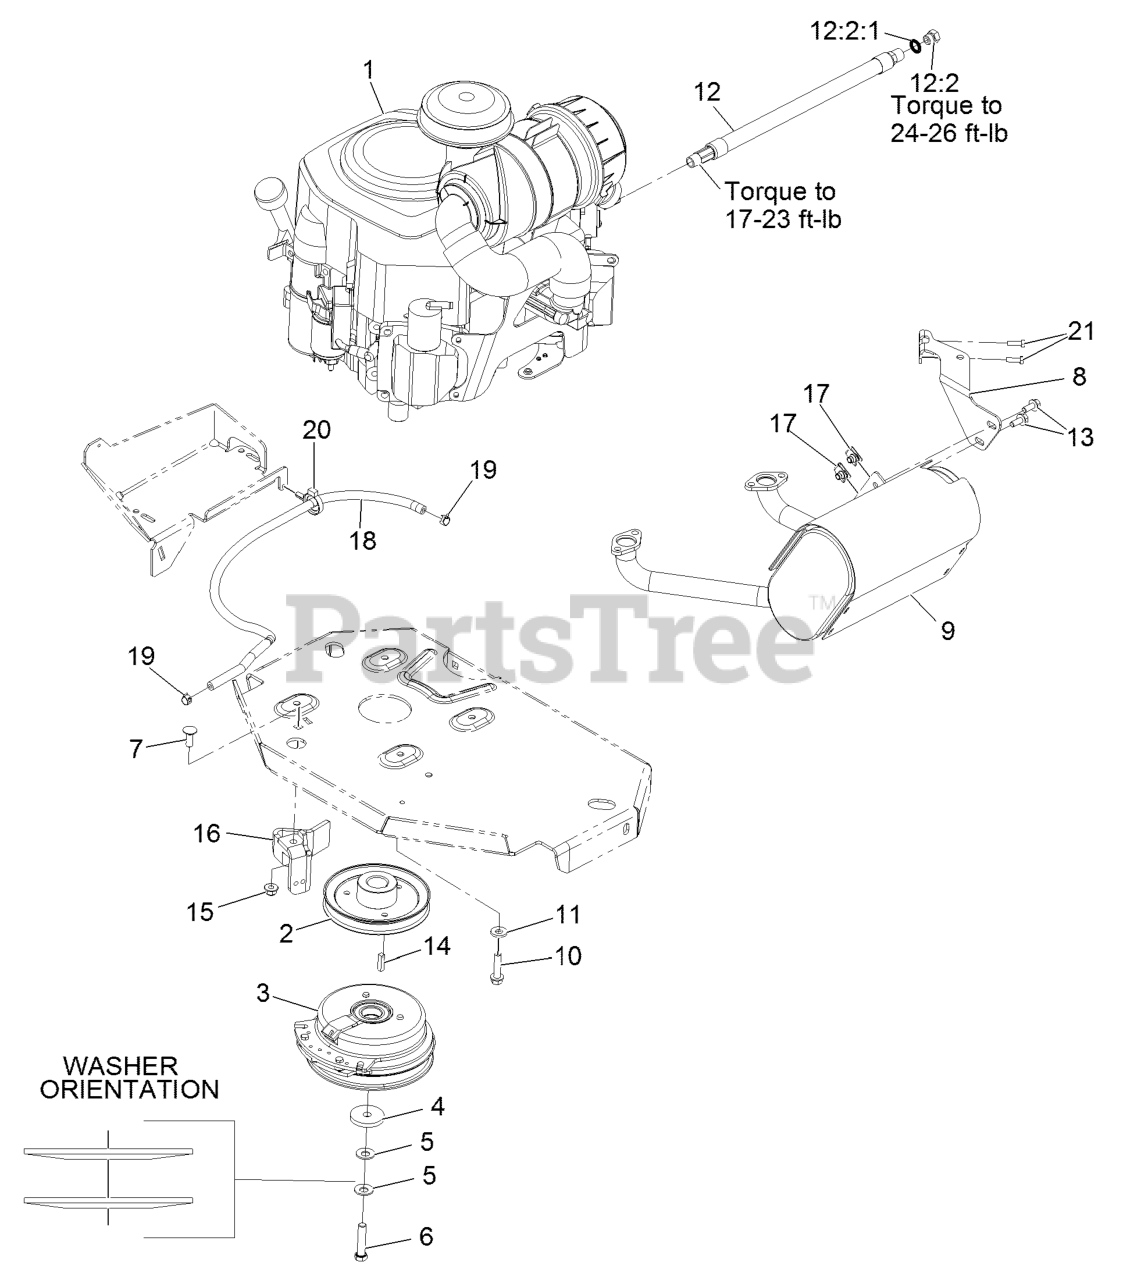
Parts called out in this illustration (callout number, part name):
2	SHEAVE-PUMP, DRIVE
3	CLUTCH KIT
4	WASHER-CLUTCH
5	WASHER-SPRING
6	SCREW-HH W/LOCTITE
7	SCREW-CARR
8	MUFFLER BRACKET KIT
10	SCREW-HWH
11	WASHER-BELLEVILLE
12	OIL DRAIN HOSE ASM
12:2	PLUG-HH
12:2:1	O-RING
13	SCREW-HHF
15	NUT-HF, NI
16	CLUTCH-ANCHOR
18	HOSE-FUEL
19	CLAMP-HOSE
20	CLAMP-HOSE
21	SCREW-HH M6-1 X 20Mm W/Patch
